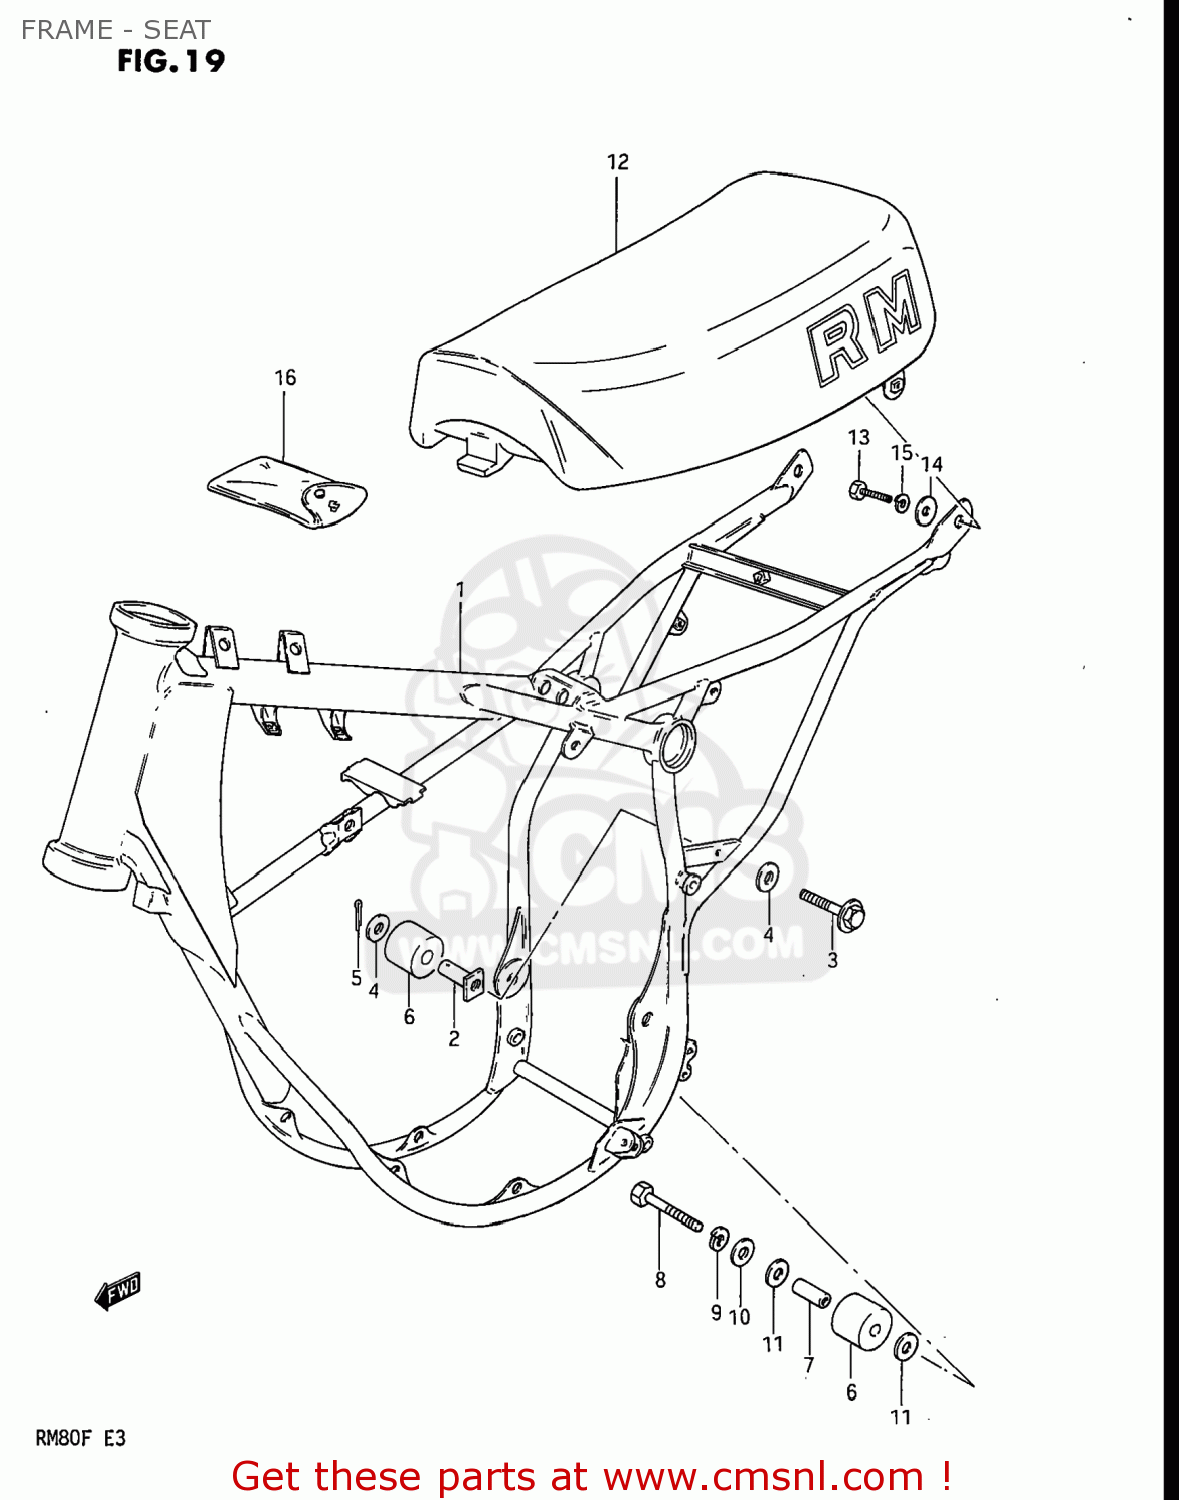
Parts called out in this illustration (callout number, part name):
1	FRAME
2	BOSS,CHAIN CONTROL
3	BOLT
4	WASHER
5	PIN 25X20
6	ROLLER,CHAIN LENGTH CONTROLLER
7	SPACER (6.5X10.5X29)
8	BOLT
9	WASHER,LOCK
10	WASHER, LOWER
11	WASHER
12	SEAT ASSEMBLY
13	BOLT
14	WASHER (6.5X18X1.6)
15	WASHER,LOCK
16	TOOL SET
